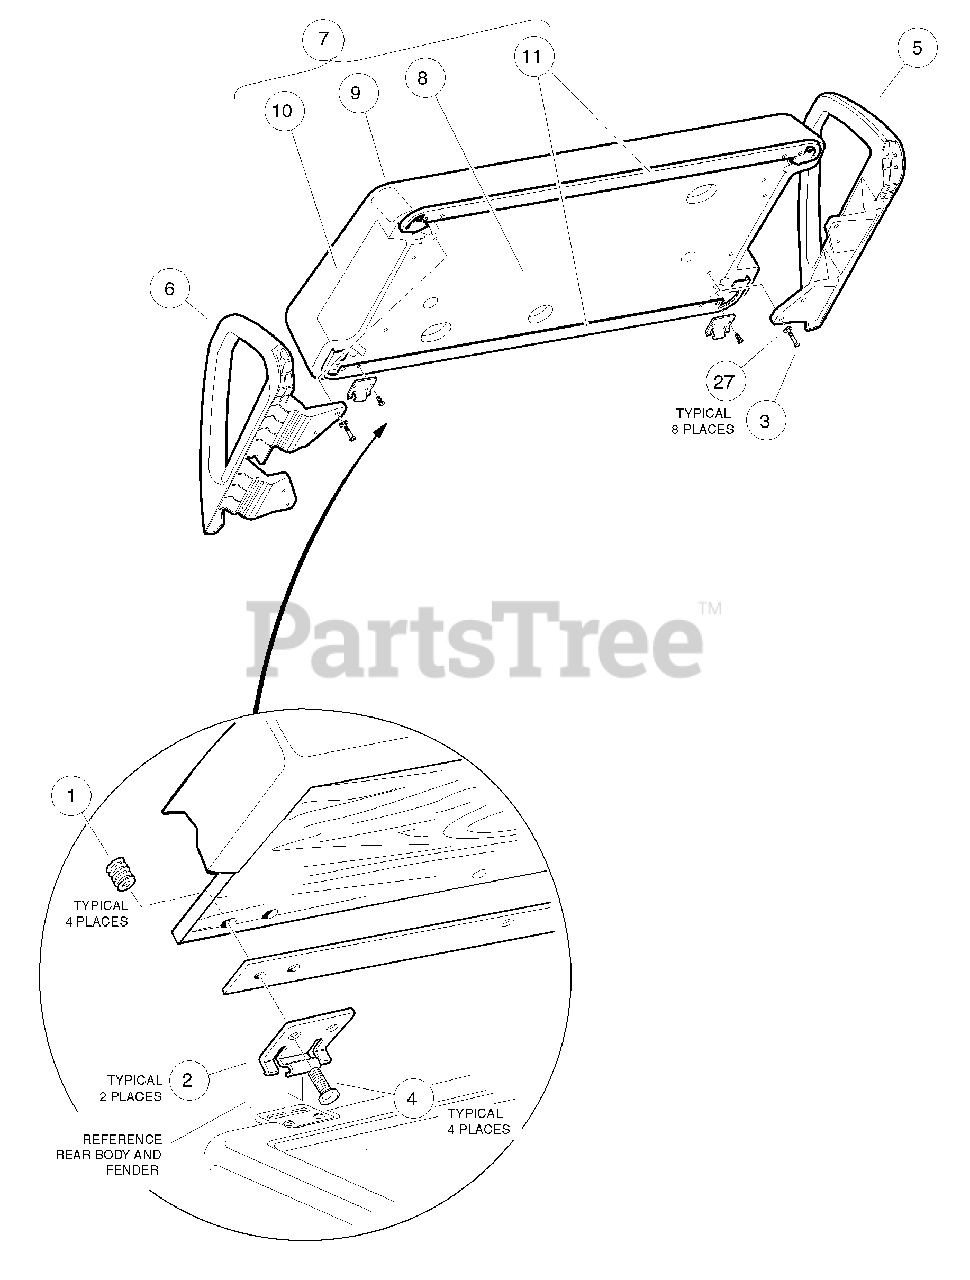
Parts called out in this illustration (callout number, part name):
1	Insert - Wood
2	Hinge Plate
3	Screw, 1/4-20 X 1.50 Hex-Head Cap
4	Screw, 1/4-20 X 0.75 Hex-Head Cap
5	Armrest, Passenger
6	Armrest, Driver
7	Seat Bottom Assembly, Buff
8	Plywood Assy
9	Vinyl Cover, Seat Bottom, Buff
10	Foam, Seat
11	Gasket, Seat
12	Seat Bottom Assembly, White
13	Plywood Assy
14	Vinyl Cover, Seat Bottom, White
15	Foam, Seat
16	Gasket, Seat
17	Seat Bottom Assembly, Black
18	Plywood Assy
19	Vinyl Cover, Seat Bottom, Black
20	Foam, Seat
21	Gasket, Seat
22	Seat Bottom Assembly, Gray
23	Plywood Assy
24	Vinyl Cover, Seat Bottom, Gray
25	Foam, Seat
26	Gasket, Seat
27	Washer, 1/4 Type A Narrow Flat
